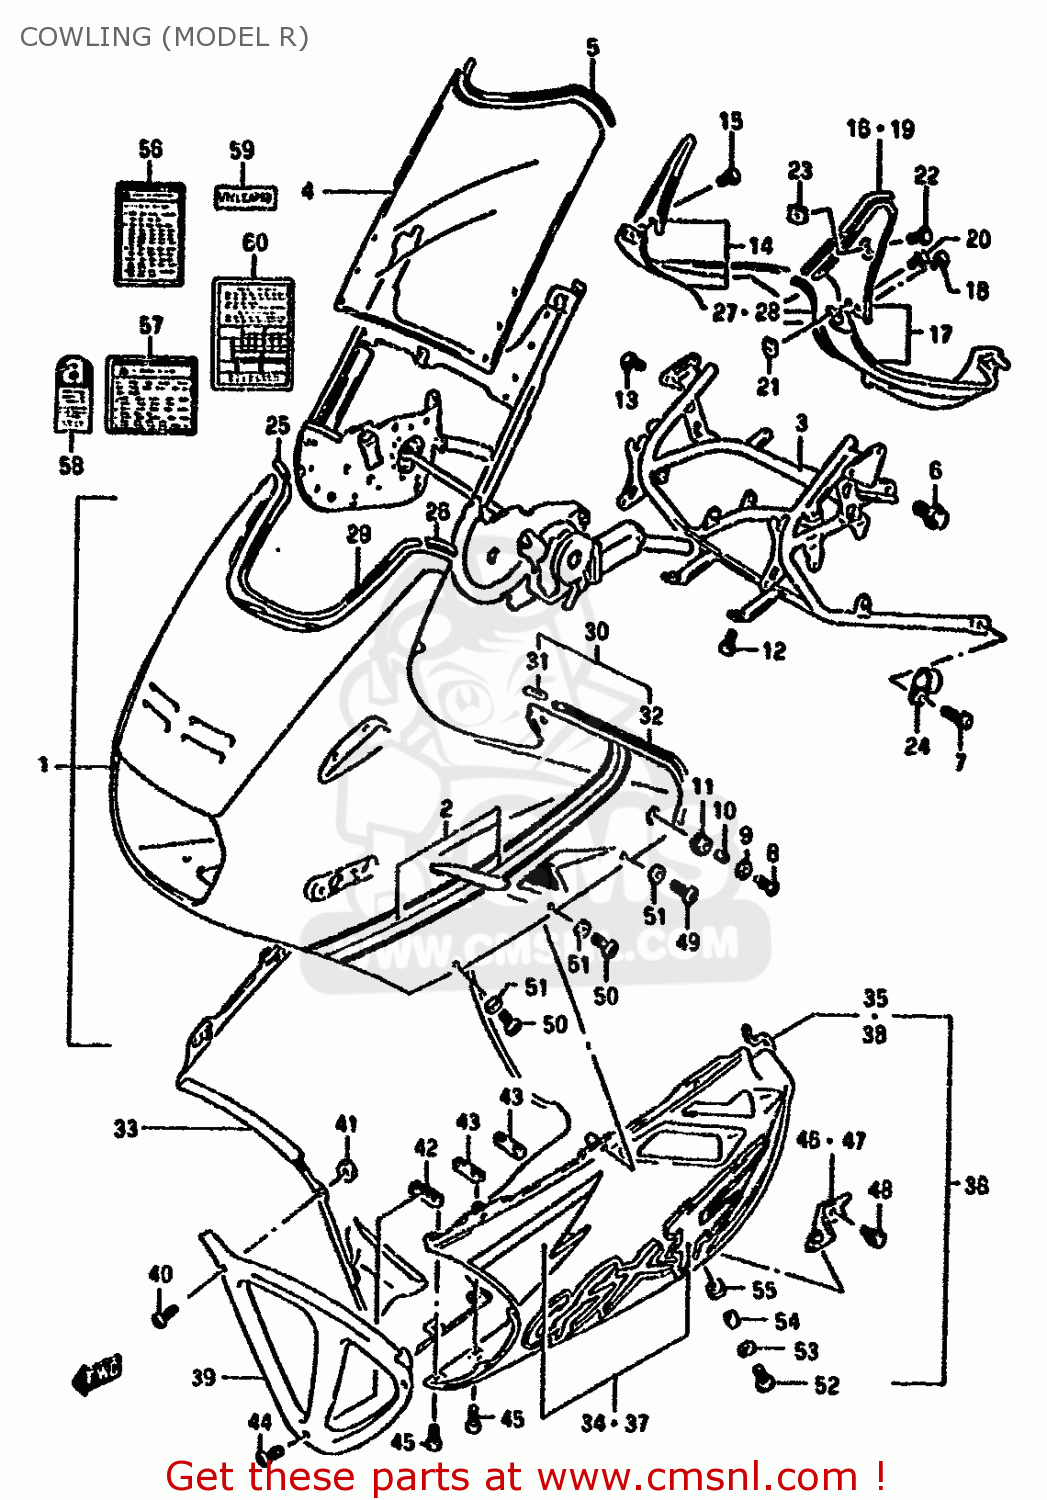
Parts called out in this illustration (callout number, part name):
1	BODY ASSY,COWLING
2	TAPE SET,COWL,
3	BRACE,COWLING
4	WINDSCREEN
5	MOLDING
6	BOLT(10X12)
7	BOLT
8	SCREW(6X20)
9	WASHER(6.5X18X1)
10	SPACER
11	CUSHION
12	SCREW(6X16)
13	SCREW 6X12
14	PANEL ASSY,R
15	SCREW
16	MOLDING,COWL.
17	PANEL ASSY,L
18	SCREW
19	MOLDING,COWL.
20	SCREW 5X12
21	NUT
22	SCREW L:12
23	NUT
24	CLAMP
25	CAP,PANEL & COWLING,R
26	CAP,PANEL & COWLING,L
27	MOLDING,COWLING PANEL,R
28	MOLDING,COWLING PANEL
29	MOULDING
30	MOLDING,COWLING BODY SIDE
31	COVER,MOLDING END
32	MOLDING,COWLING BODY SIDE
33	COVER ASSY,COWL LOWER RH (BLACK)
34	TAPE SET,RH
35	MOLDING,COWLING,LOWER
36	COVER ASSY,COWL LOWER LH (BLACK)
37	TAPE SET,LH
38	MOLDING,COWLING,LOWER
39	COVER,COWLING,LOWER,FRONT
40	SCREW(5X14)
41	NUT
42	BRACE,COWLING LWR COVER
43	BRACE,COWLING LWR COVER RR
44	SCREW(6X12)
45	SCREW(6X16)
46	BRACE,COWLING LWR,R
47	BRACE,COWLING LWR,L
48	BOLT
49	SCREW(6X20)
50	SCREW(6X16)
51	WASHER
52	SCREW(6X20)
53	WASHER(6.5X18X1)
54	SPACER(6.4X9.2X12)
55	CUSHION
56	LABEL (WARNING SCREEN)
57	LABEL, WARNING SAFETY
58	LABEL,ASBESTOS WARNING
59	LABEL,CAUTION
60	LABEL,TIRE AIR PRESSURE
61	LABEL,ASBESTOS WARNING
62	LABEL,CAUTION
63	LABEL,TIRE AIR PRESSURE
